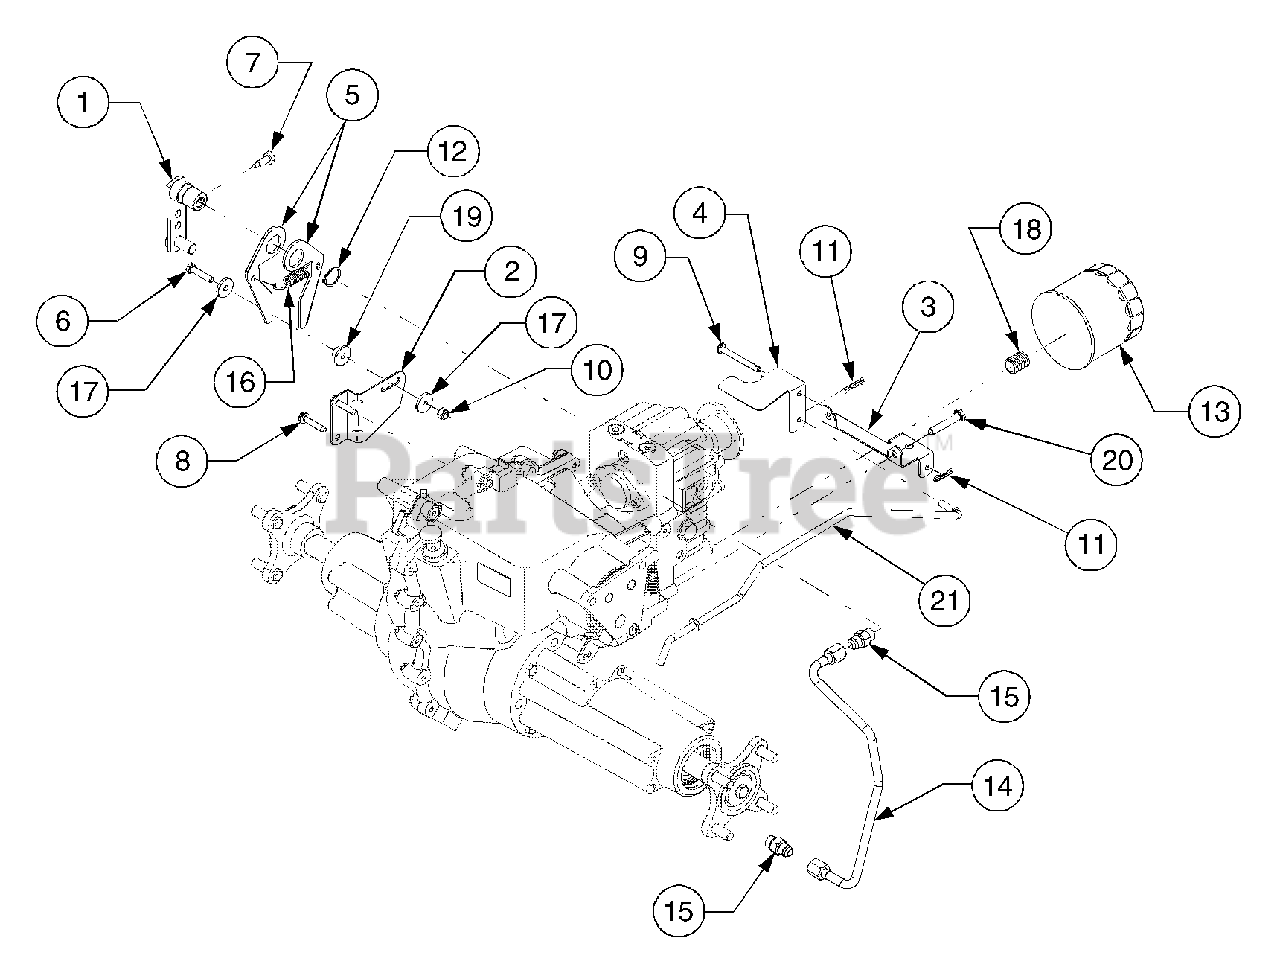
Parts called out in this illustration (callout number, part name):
1	Arm Assembly, Control
2	Bracket, Hydro Neutral
5	Arm, Neutral
6	Screw, Hex Cap, 1/4-20 x 1.25
7	Screw, Special Hex Cap, 5/16-24 x .625
8	Screw, Hex Wash TT-Tap, 1/4-20 x 1.25
9	Pin, Clevis, .25 x 2.38
10	Nut, Hex Top Lock, 1/4-20
11	Pin, Internal Cotter
12	Ring, Snap, .875 Shaft
13	Filter, Oil
14	Tube, Hydro Inlet
15	Connector, w/O-Ring
16	Spring, Extension, .5 OD x 1.97
17	Washer, Flat, .25 x .93 x .120 Thk
18	Nipple, Oil Filter
19	Spacer, Centering
20	Screw, Hex Cap, 5/16-18 x 1.75 GR5
21	Rod, Hydro Dump Valve
